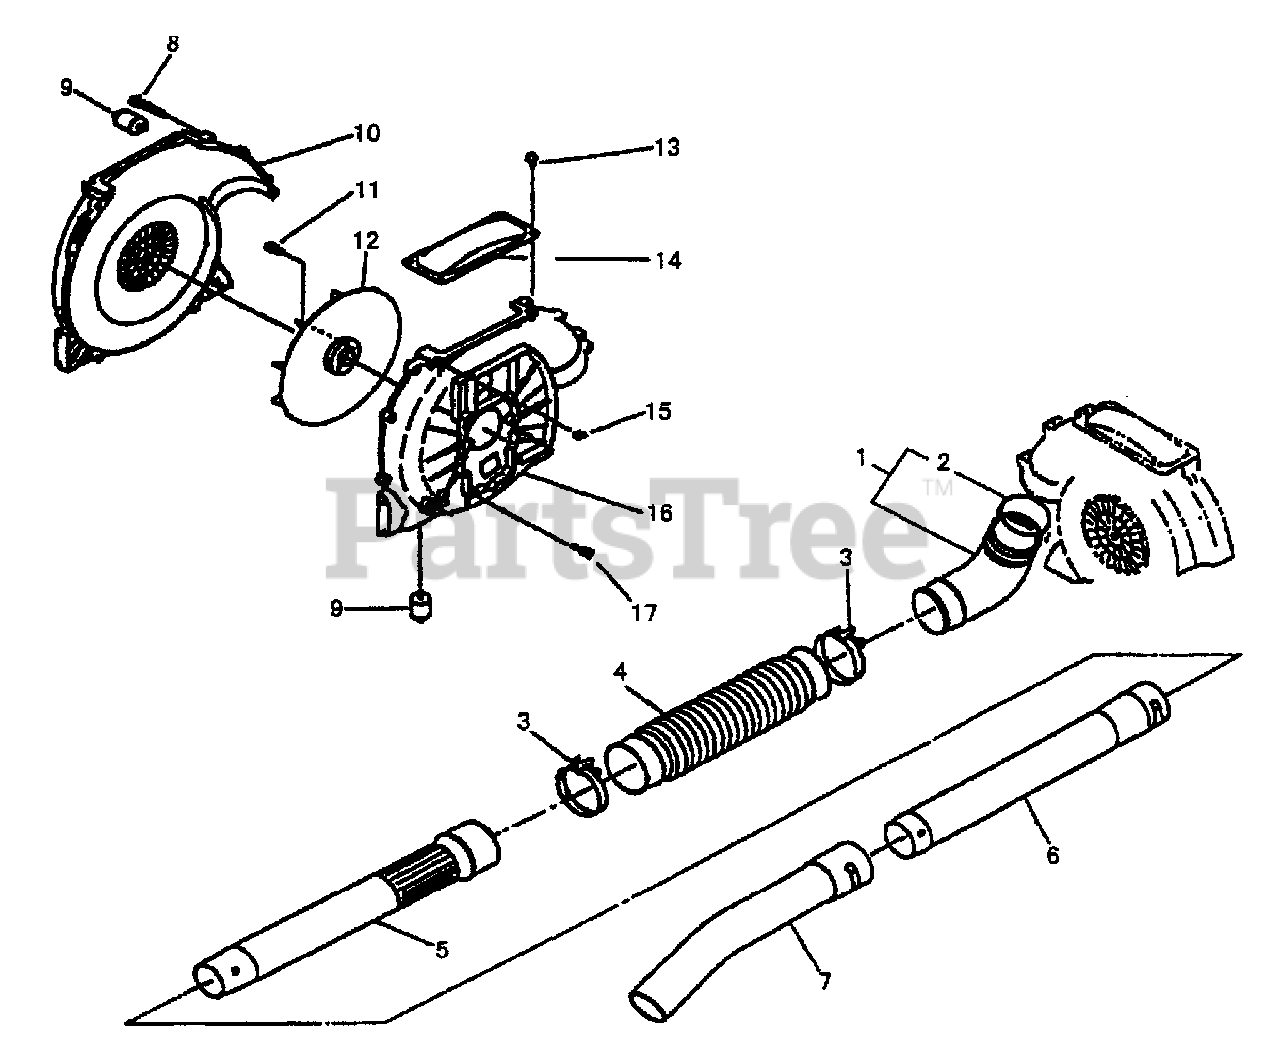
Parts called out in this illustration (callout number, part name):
1	Elbow Pipe Compl.
2	O-Ring
3	Clamp
4	Flexible Pipe
5	Base Pipe
6	Middle Pipe
7	Bend Pipe
8	Tapping Screw (M5x30)
9	Rubber AV Mount
10	Fan Housing
11	Pre-Coat Lock Bolt
13	Screw (M6x20)
15	Hex Nut
16	Fan Housing
17	Pre-Coat Lock Bolt
